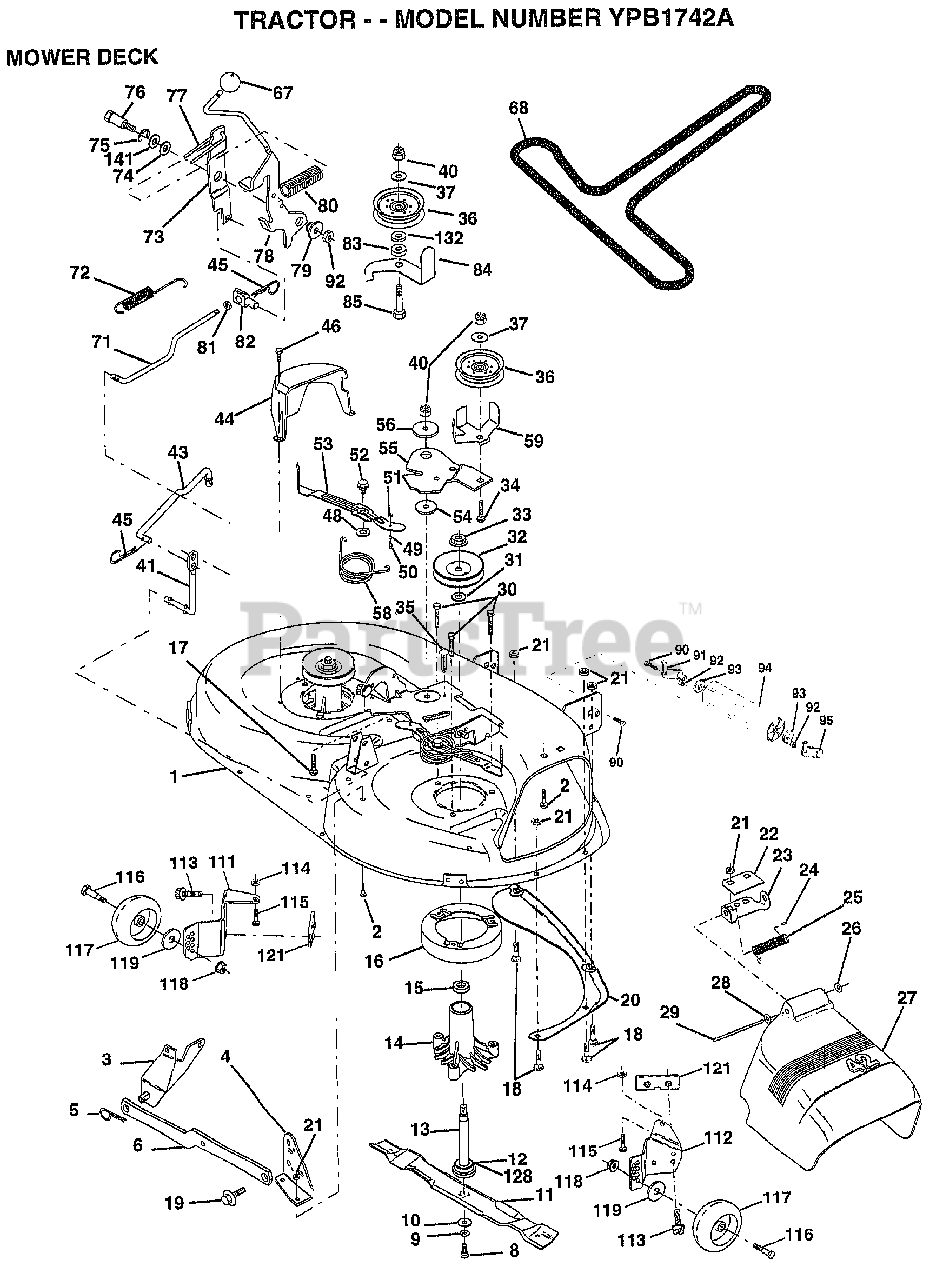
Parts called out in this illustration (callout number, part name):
1	"HOUSING ASSY.42"""
2	BOLT
3	BRKT ASM SWAY BAR
4	BRKT DECK SW BAR
8	BLADE BOLT
10	WASHER.HARD.BLADE
11	"BLADE.42"" HIPERF"
12	BEARING.BALL
14	HSG ASM MANDREL
15	BEARING
16	STRIPPER RND MWR
17	BOLT RDHD 3/8-16
18	BOLT
19	BOLT SHD 5/16-18
20	BAFFLE VORTEX 42
22	STIFFENER BRKT
23	DEFLECTOR BRKT
24	CAP-SLEEVE LT
25	SPRING TORSION
26	NUT PUSH M
27	DEFLECTOR.SHIELD
28	WASHER
29	HINGE ROD
30	"SCREW-THD ROLL,WA"
31	WASHER
32	PULLEY.MANDREL.42
34	BOLT
35	XMAS TREE FASTNER
36	FLAT IDLER PULLEY
37	WASHER
41	PIVOT ROD
43	ROD CLUTCH W/NIBS
44	GUARD MAND LH BLK
45	RETAINER M
46	SCREW.1/4-20X5/8
48	HARD SMALL WASHER
49	ROLLER ASM-CAM
50	SHOULDER BOLT
51	LOCKNUT
52	BOLT.SHLD.5/16-18
53	BRAKE PAD ARM ASM
54	HARDENED WASHER
55	ARM-IDLER
56	SPACER RETAINER
58	SPRING TORSN BRAK
59	GUARD IDLER TUV
67	KNOB.RD.7/16-14
68	BELT.V.T-PATH
71	ROD CLUTCH 38/42
72	RETURN SPRING
73	CLUTCH ARM SECOND
74	WASHER
75	RING
76	SHOULDER BOLT
77	SPRING KEEPER
78	LEVER.ASM.CLUTCH
79	BUSHING
80	SPRING.CLUTCH.MWR
81	NUT
82	TRUNION ADJ
83	WASHER
84	"KEEPER-BELT,FIXED"
85	BOLT
90	BOLT
92	NUT
93	WASHER
111	BRACKET.GWHL.LH.
112	BRACKET.GWHL.RH.
113	SCREW
116	BOLT M
117	WHEEL.GUAGE
118	LOCKNUT
119	WASHER
121	BRACKET.EXTRD.GWL
128	WASHER.FELT.
132	WASHER GT
141	WASHER .T
